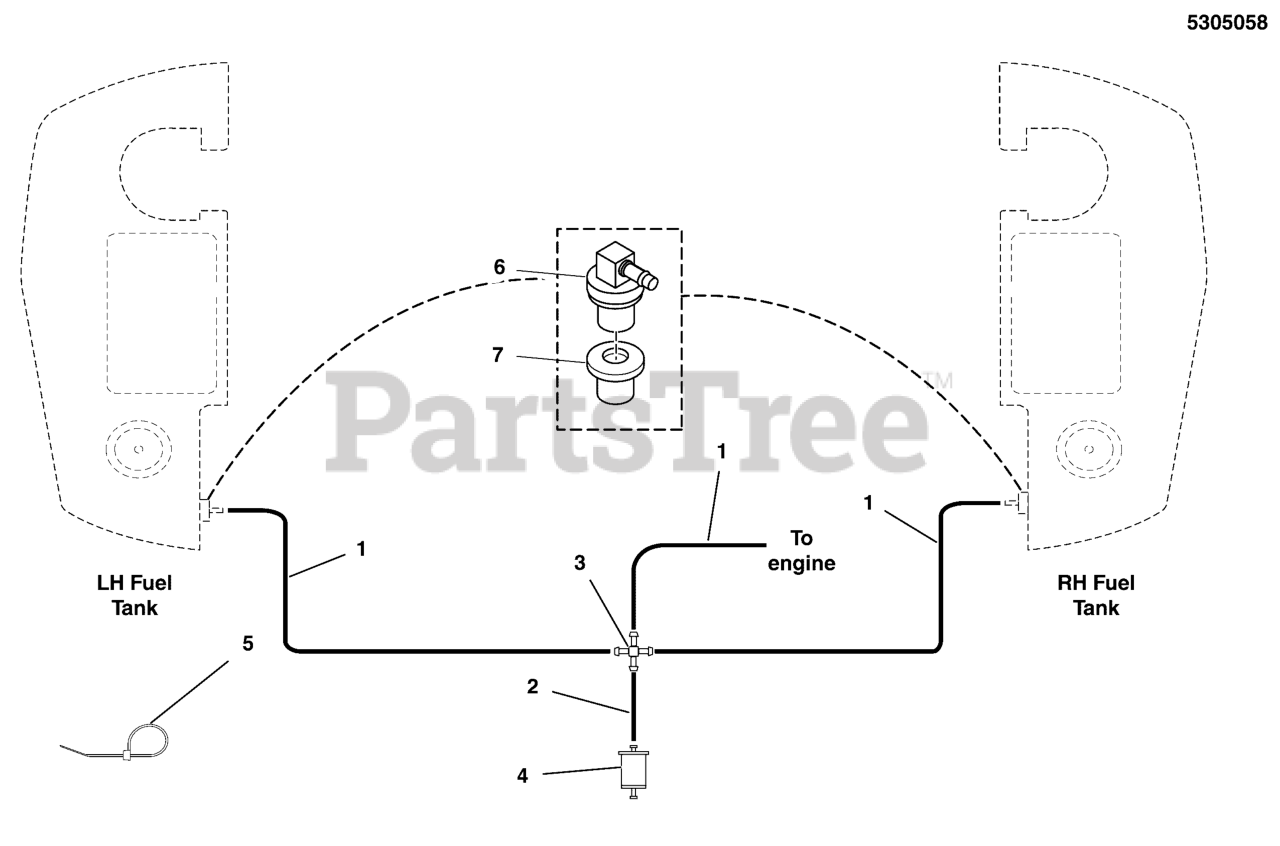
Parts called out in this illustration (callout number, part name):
1	HOSE, VAPOR, 5MM ID, 34.50 LG
2	HOSE, VAPOR, 5MM ID, 3.00 LG
3	FITTING, BARBED CROSS, 3/16" BLK NYLON
4	FILTER, FUEL
5	TIE,SELF-LOCKING, 6"
6	REMOTE VENT ASSEMBLY
7	GROMMET
